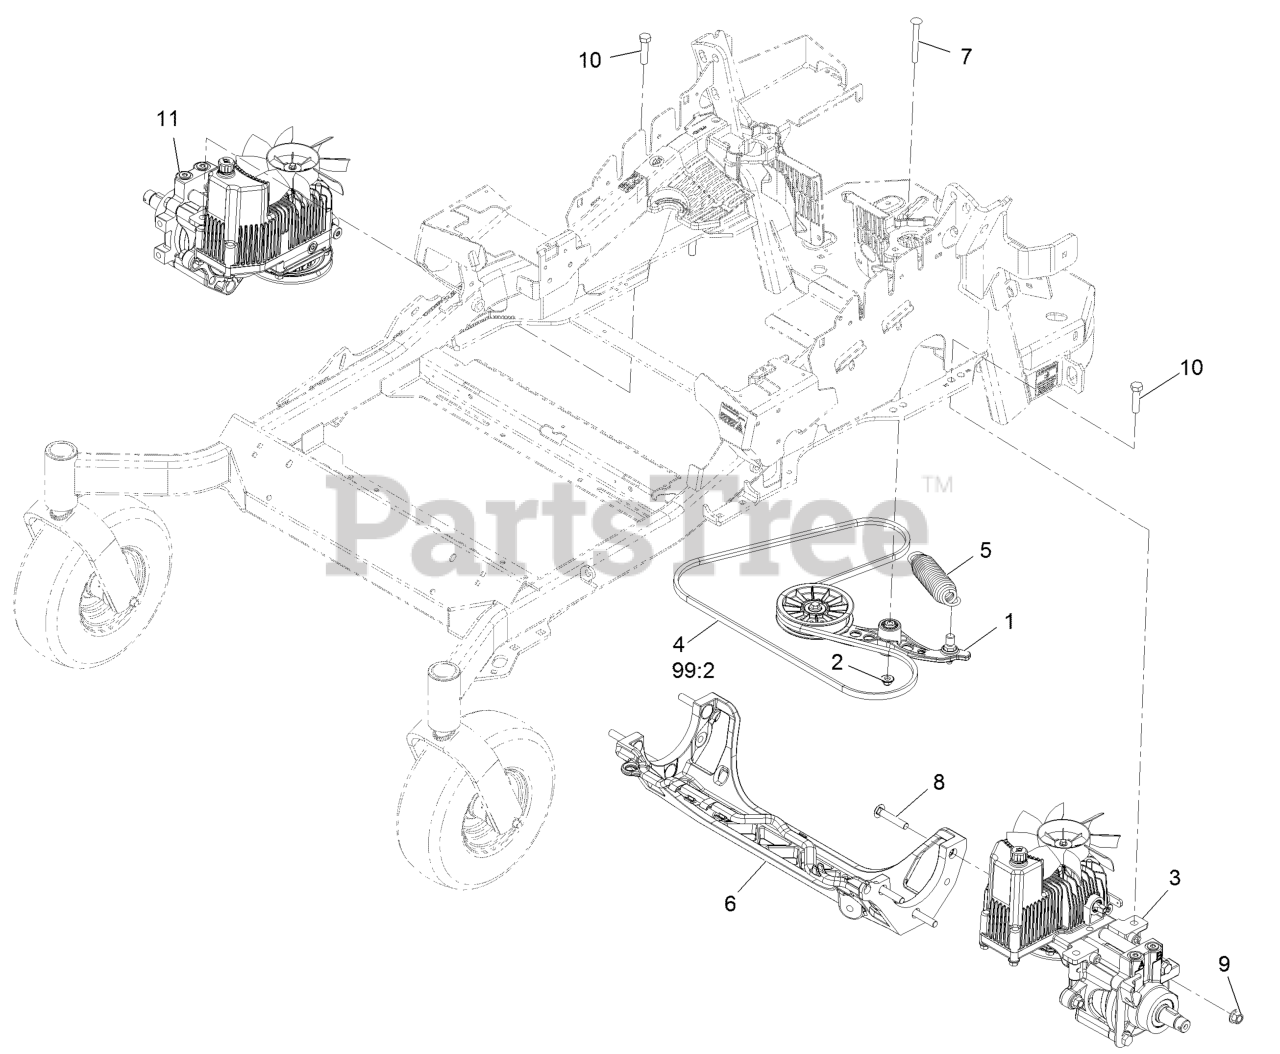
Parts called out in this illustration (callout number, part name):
1	PUMP IDLER ASM
2	Nut-Nyloc 3/8-16 Flg
4	BELT
5	SPRING-EXTENSION
7	BOLT-SHOULDER, CARRIAGE 3/8-16 X 3 1/2
8	SCREW-CARR
9	Nut-Lock 1/2-13
10	SCREW-HH
99	BOTTLE-OIL, 32OZ HYDRAULIC
99:2	BELT
